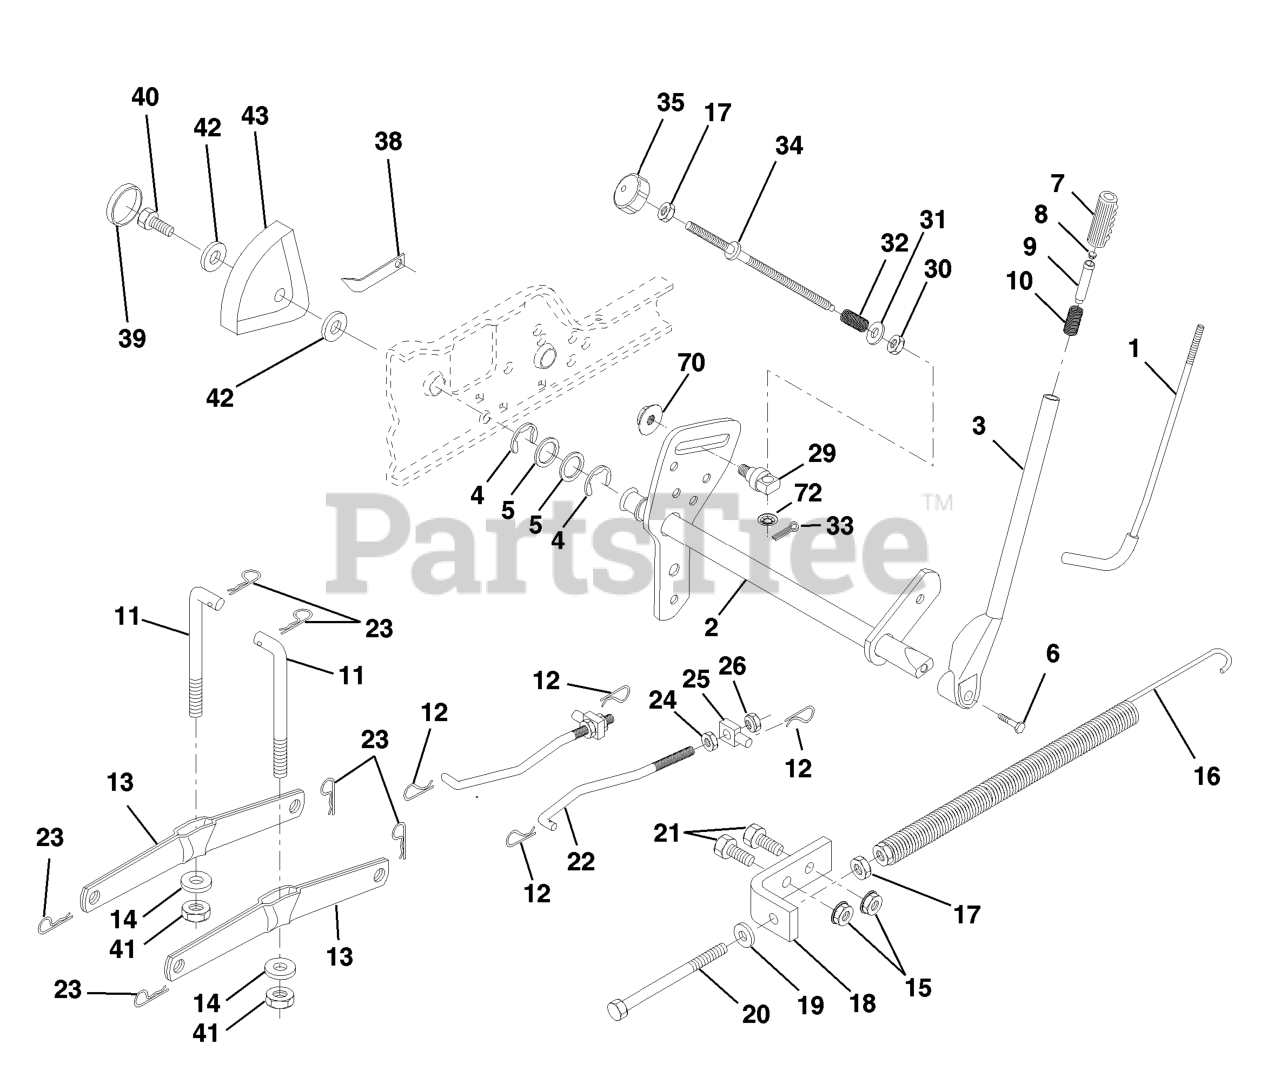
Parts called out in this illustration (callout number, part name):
1	LEVER ROD LT
2	SHAFT ASM., LIFT VGT
3	LEVER ASSY-LIFT RH
5	Washer 29/32 x 1-1/4 x 16 Ga.
6	BOLT
7	GRIP HANDLE
8	PLUNGER BUT KIT
9	PLUNGER BUT KIT
10	SPRING**
11	LINK LIFT
12	SPRING RETAINER
13	ARM.REAR.SUSPENSION
14	BEARING PIVOT
16	LIFT SPRING
17	NUT
19	WASHER
21	BOLT
22	FRONT LINK
23	RETAINER-SPRNG RB
24	NUT.HEX.JAM.1/2-13
25	TRUNION
26	NUT LTV
32	SPRING.COMP.INF.H
33	COTTER PIN
34	ROD.LIFT.ADJUSTABLE
35	KNOB INF 3/8-16
38	POINTER, HEIGHT INDICATOR(2 2)
40	SCREW.THDROL.5/16-18X3/4.TTY
41	NUT CROWNLOCK 3/8-24
43	HEIGHT INDICATOR
70	NUT
72	NUT PUSH M
